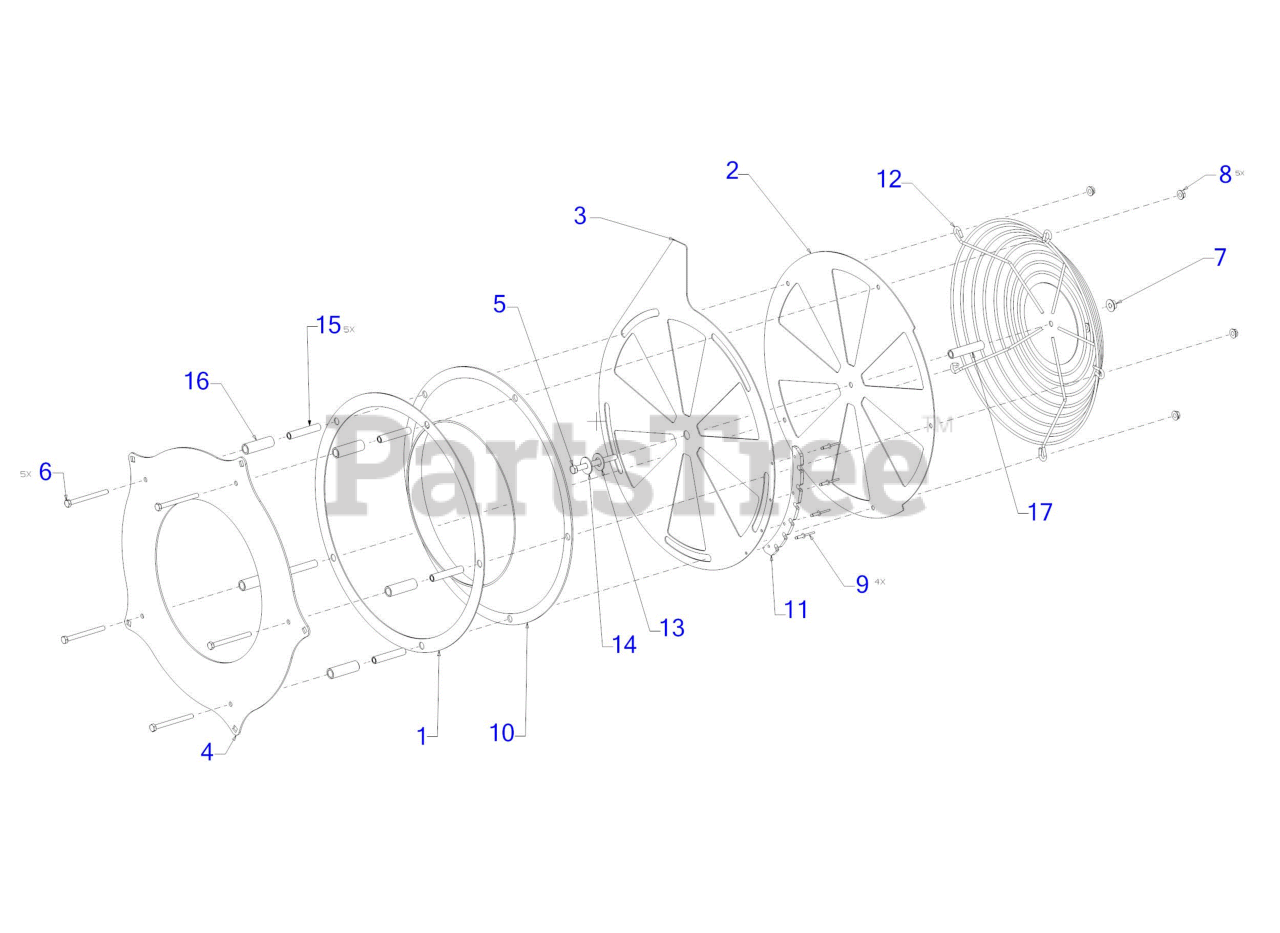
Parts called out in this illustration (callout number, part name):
5	SCREW 3/8-16 x 3.75 GR5
6	SCREW 5/16-18X3.5 GR5
7	FLANGE LOCK NUT
8	FLANGE NUT
9	POP RIVET .187 DIA
10	BLOWER INLET BELL
11	BLOWER IRIS RING GEAR
13	FLAT WASHER NYLON 5/8
14	SHOULDER SPACER
15	SPACER .5 X .334 X 2.75
16	TUBE SPACER .75 X .525 X 2.375
17	SPACER .625 X 4.06 X 2.87
